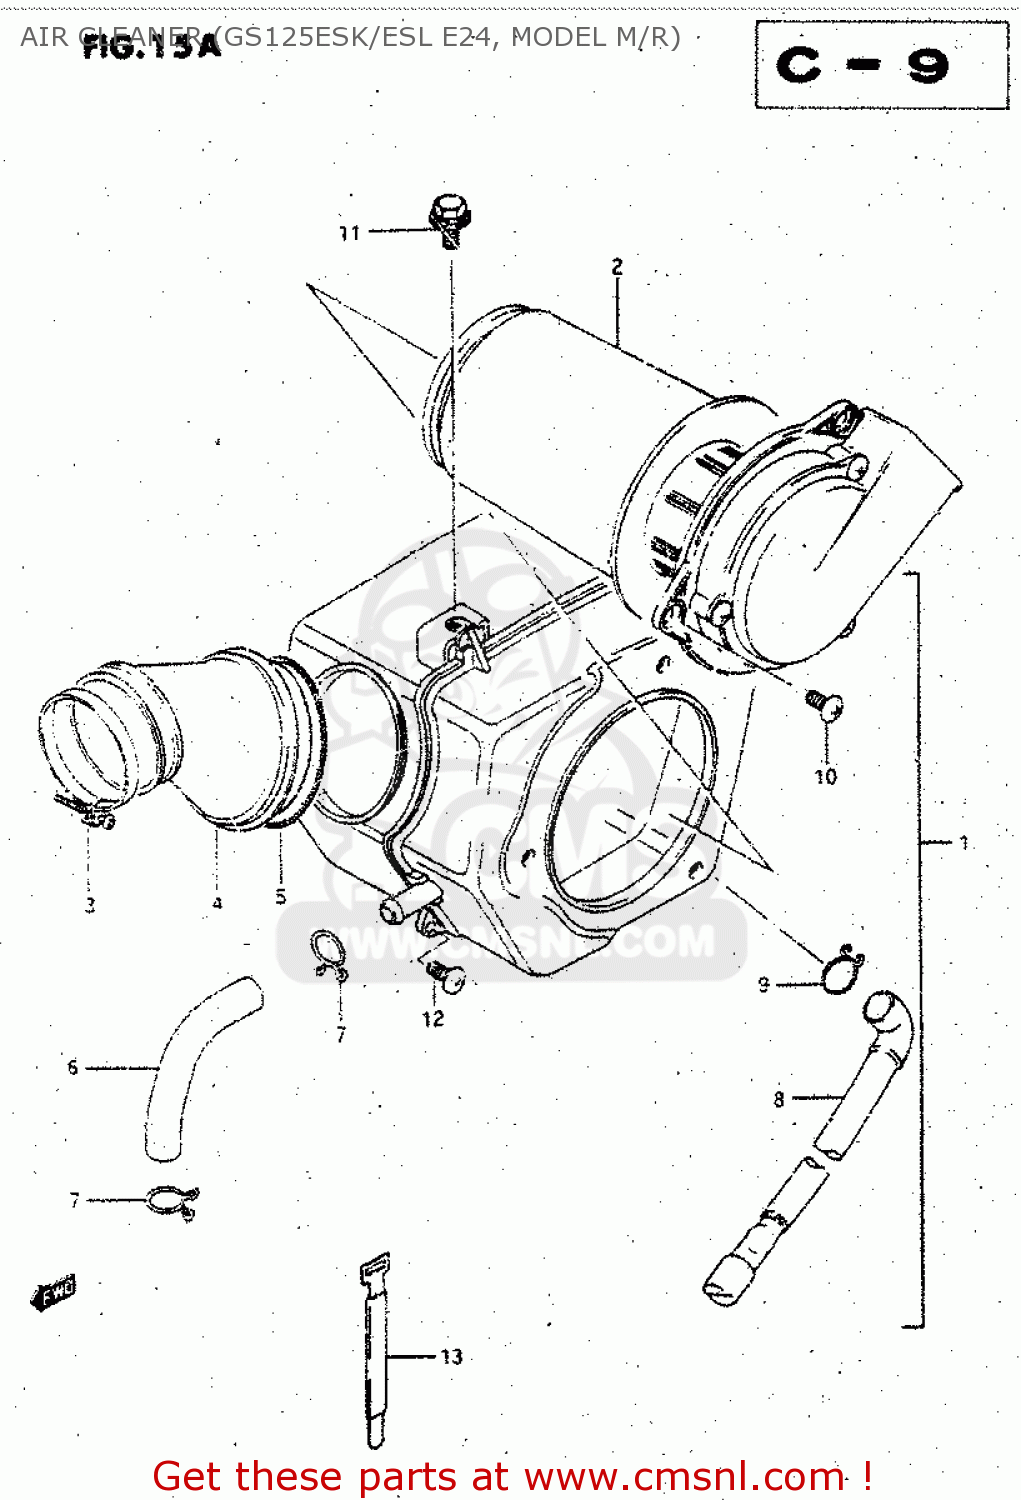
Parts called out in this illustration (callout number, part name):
1	CLEANER ASSY,AIR
2	FILTER
3	CLAMP
4	TUBE,OUTLET
5	CLAMP,AIR CLEANER SIDE
6	TUBE,BREATHER
7	CLIP,BREATHER TUBE
8	TUBE,DRAIN
9	CLIP
10	SCREW
11	BOLT(6X16)
12	SCREW
13	CLAMP L:110
